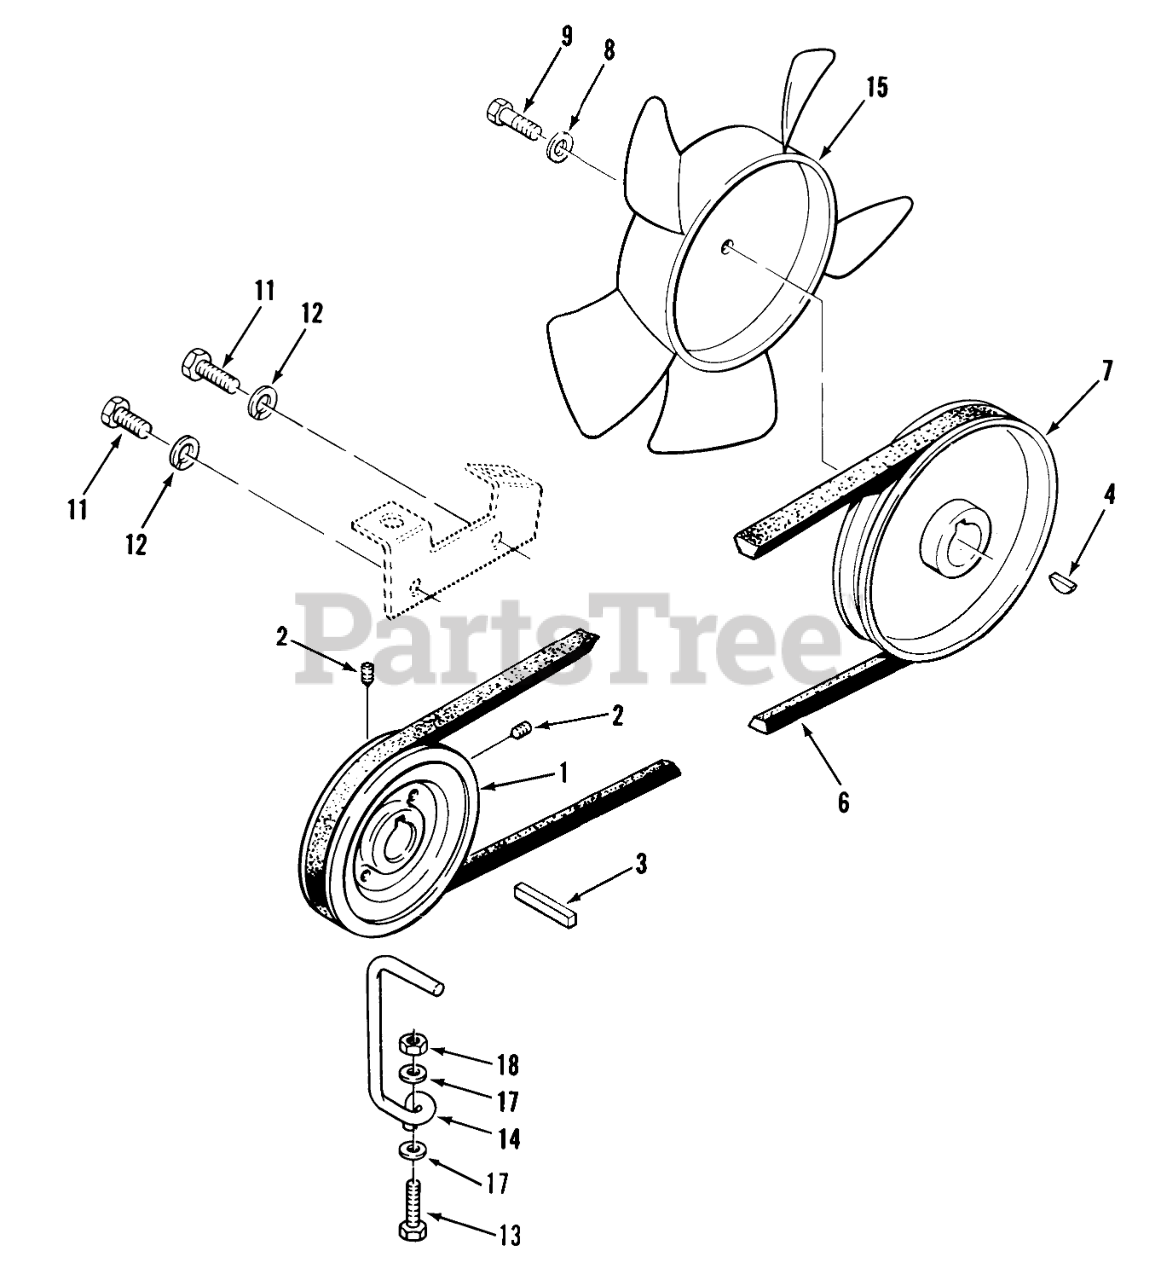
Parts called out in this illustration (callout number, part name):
1	PULLEY
2	Set Screw
4	KEY WOODR 1/8X1/2 DI
4	KEY-WOODRUFF
6	BELT-V
7	SHEAVE HYDRO INPUT
7	PULLEY
8	WASHER
9	HEX HD CAP SCREW -4
9	H H C S
11	BOLT
12	LOCKWASHER
13	Bolt
14	GUIDE-BELT BOTTOM B
15	NYLON FAN-L-CW
17	Collar
18	Nut
